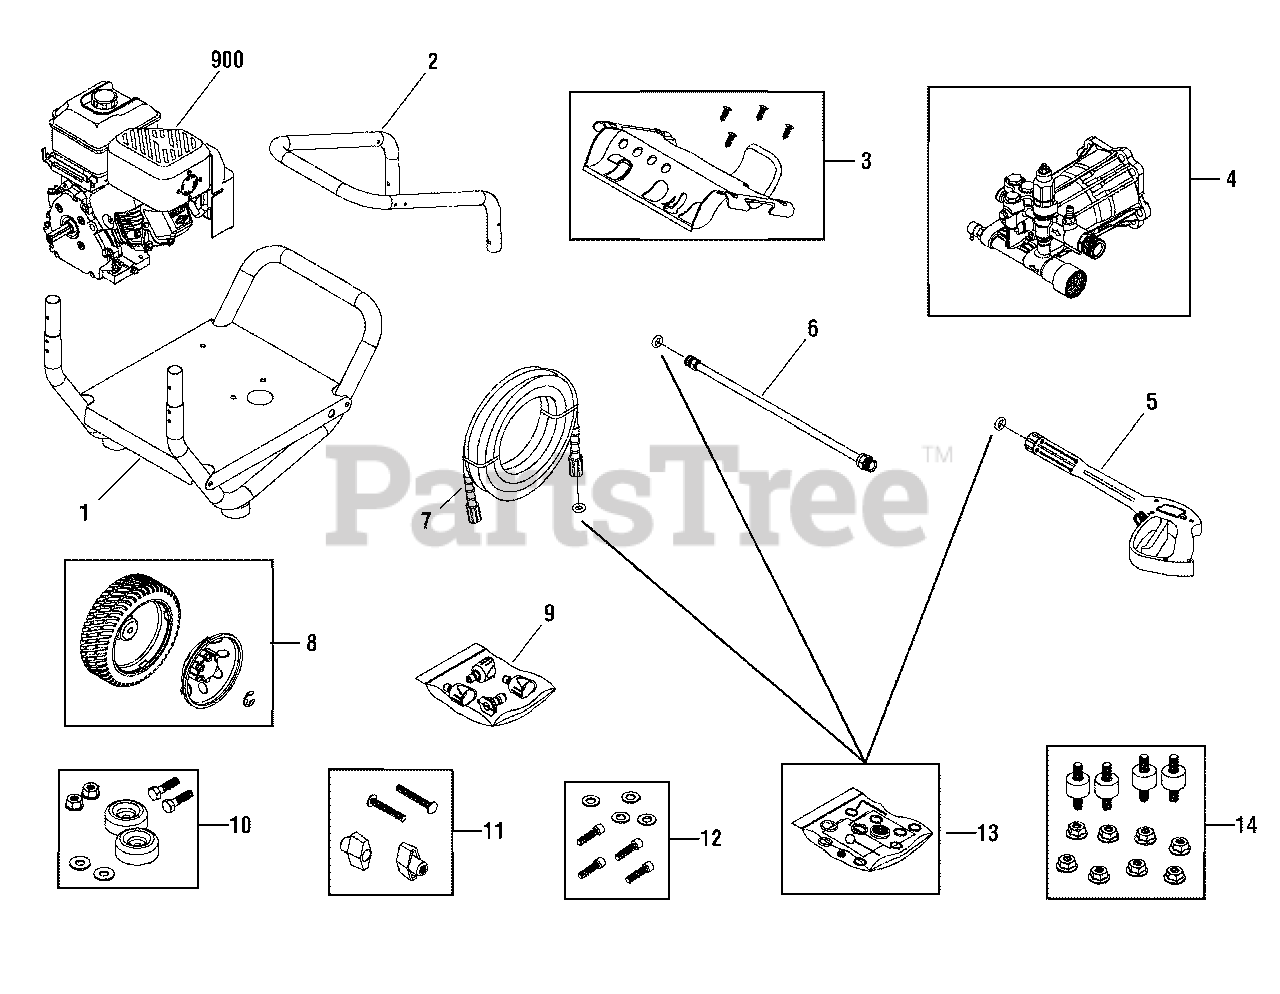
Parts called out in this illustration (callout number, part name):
5	GUN
6	EXTENSION
9	KIT, QC Nozzles
10	MOUNT, Vibration
11	KIT, Hardware, Handle
12	KIT, Hardware, Pump Mounting
13	KIT, O-Ring
14	KIT, Vibration Mount
900	* ENGINE
